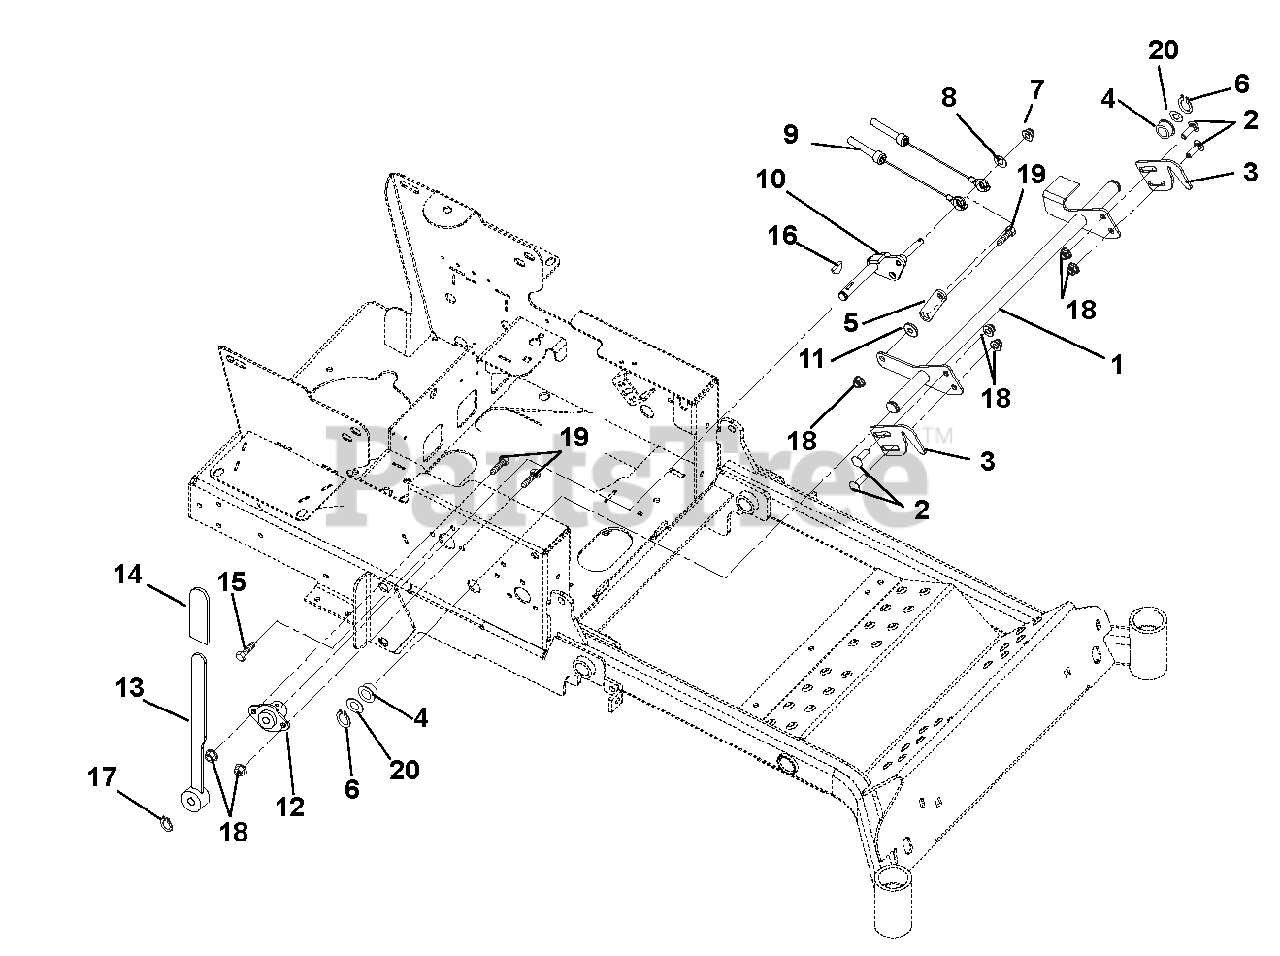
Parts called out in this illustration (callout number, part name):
1	WMT, NEUTRAL INTERLOCK
2	@BLT-RDHDSQNK .31-18X1.00 G5YZ
3	NEUTRAL LOCK LATCH - BLACK
4	BSHG-FLG .750X1.000X.625X1.250
5	PLATE, NEUTRAL INTERLOCK
6	RG-RTNG-EXT .689X.078
7	NUT-PUSH .312
8	@WSHR-FL-STL.344X.688X.065YWZC
9	CABLE, BRAKE ACTUATING
10	WMT, PARK BRAKE ARM
11	BSHG, FLG .325X.499X.26X.88
12	BUSHING, FLANGED
13	WMT - PARKING BRAKE ARM
14	GRIP, PARKING BRAKE (YELLOW)
15	@SCR-TAP .38-16X1.00 HWH TR YZ
16	KEY-WDRF .13X.63 HRD#5
17	RG-RTNG-EXT .500X.050 (SNAP)
18	@NUT-LK-NYL-FLG .31-18 YWZC
19	@BLT-HEX .31-18X1.00 GR5 YWZC
20	WSHR-FL-STL .812X1.370X.10 YWZ
